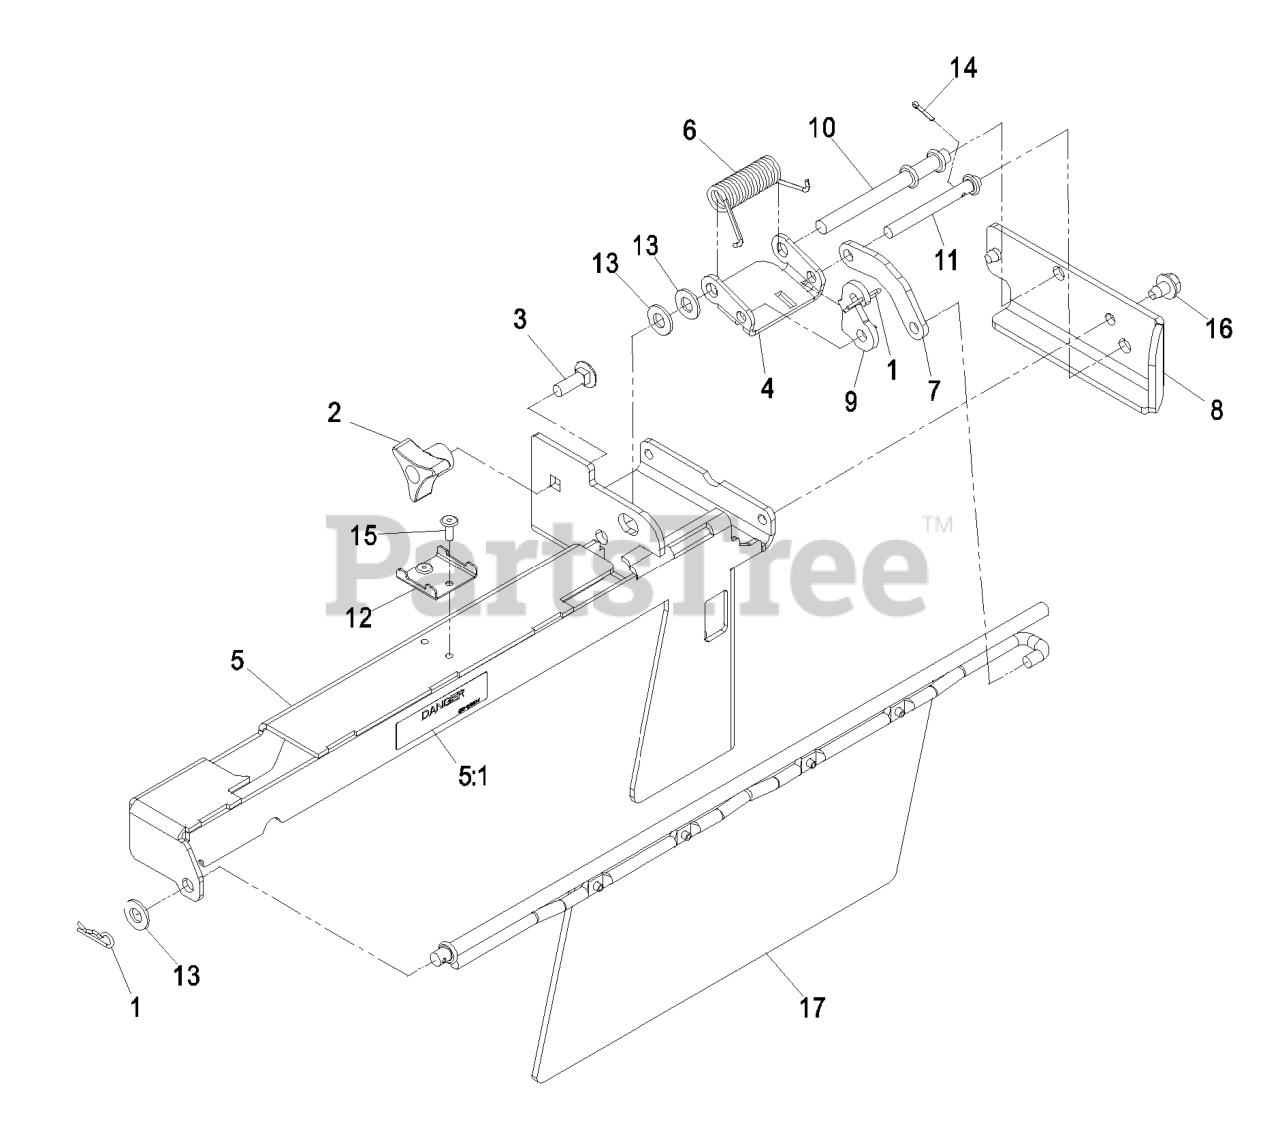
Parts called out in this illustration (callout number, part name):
1	PIN-COTTER
2	KNOB-3 PRONG
3	BOLT-CARR
4	BRACKET,LINK PIVOT
5	GATE,LINK FRAME
5:1	DECAL-COVER, MISSING
6	SPRING,TORSION
9	LINK,GATE LIFT
12	CHANNEL,LATCH CONTACT
13	WASHER-FLAT
14	PIN-COTTER
15	RIVET-BLIND
17	ASM,GATE OCD
